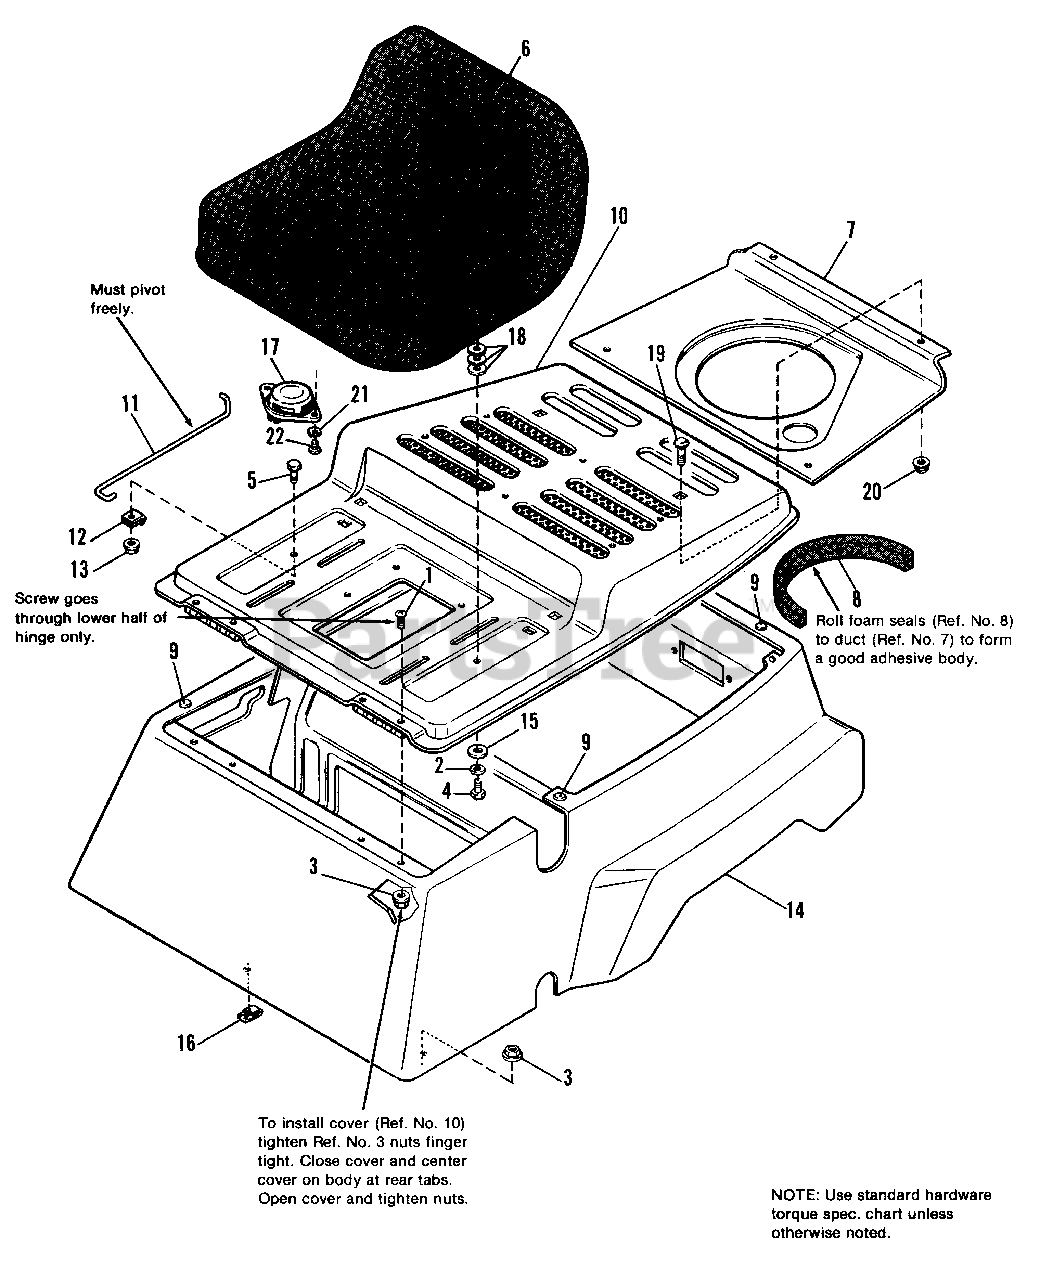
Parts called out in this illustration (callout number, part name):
1	SCREW, Truss, Phil. Hd., 5/16-18 x 1/2
2	LOCKWASHER, 5/16
3	LOCKNUT, Flange, Whiz, 5/16-16
4	CAPSCREW, 5/16-18 x 1
5	CAPSCREW, Hex, 1/4-20 x 1/2
7	DUCT, Inlet
8	SEAL, Foam (Mfg. No.1691551 Only)
8	SEAL, Foam (Mfg. No.1691535, 1691537 Only)
9	PLUG, Bumper
10	COVER ASSY.
11	ROD, Cover Support
13	LOCKNUT, Flange, 1/4-20
14	BODY ASSY.
15	WASHER, Plain, 5/16
16	NUT, Speed, 5/16-18
17	SWITCH, Seat, Operator Present
18	WASHER
19	BOLT, Carriage, #10-24 x 1/2
20	LOCKNUT, Pal, #10-24
21	LOCKWASHER, Ext. Tooth, 1/4
22	SCREW, Round Hd., 1/4-20 x 3/4
